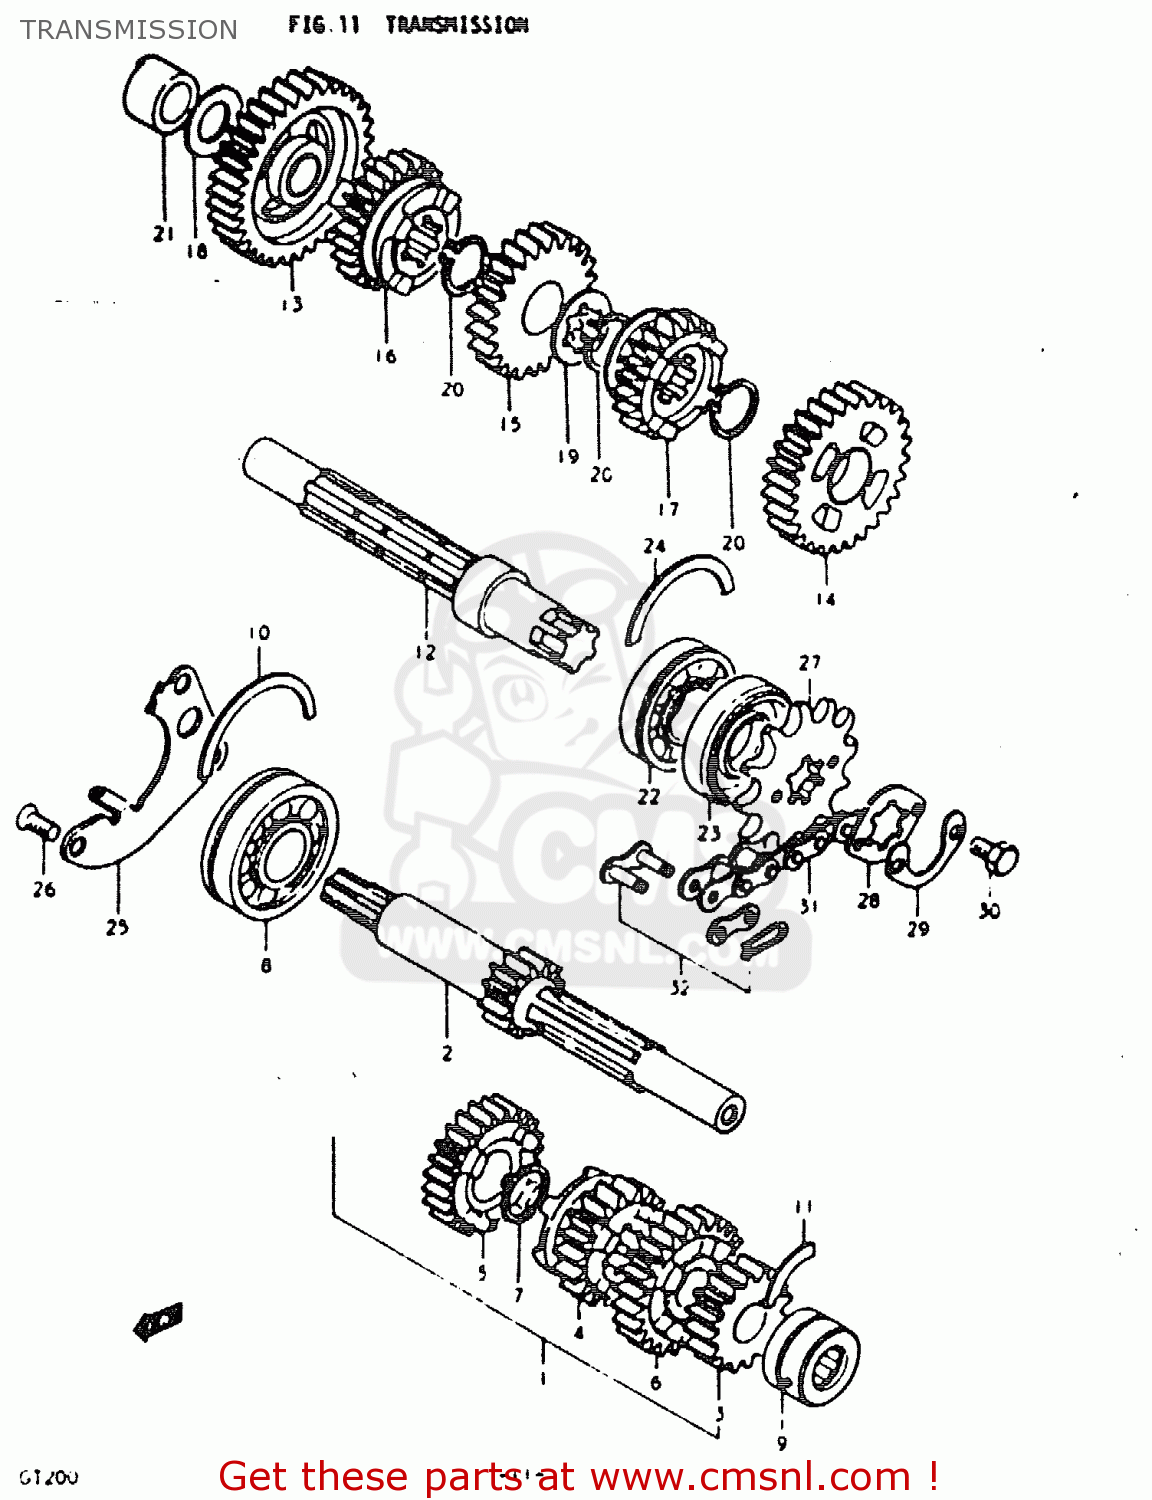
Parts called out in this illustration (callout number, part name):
1	COUNTERSHAFT ASSY
2	SHAFT, COUNTER
3	GEAR, 2ND DRIVE
4	GEAR, 3RD DRIVE
5	GEAR, 4TH DRIVE
6	GEAR, 5TH DRIVE
7	CIRCLIP
8	BEARING
9	ROLLER BEARING (15X30X1
10	C RING
11	KNOCK RING
12	SHAFT, DRIVE
13	GEAR, 1ST DRIVEN
14	GEAR, 2ND DRIVEN
15	GEAR, 3RD DRIVEN
16	GEAR, 4TH DRIVEN
17	GEAR, 5TH DRIVEN
18	THRUST WASHER
19	WASHER
20	CIRCLIP
21	BUSHING
22	BEARING(20X47X14)
23	OIL SEAL
24	C RING
25	RETAINER, COUNTER SHAFT BEARING
26	SCREW
27	SPROCKET, ENGINE
28	PLATE
29	LOCK WASHER
30	BOLT 6X10
31	CHAIN ASSY, DRIVE
32	JOINT ASSEMBLY,CHAIN
